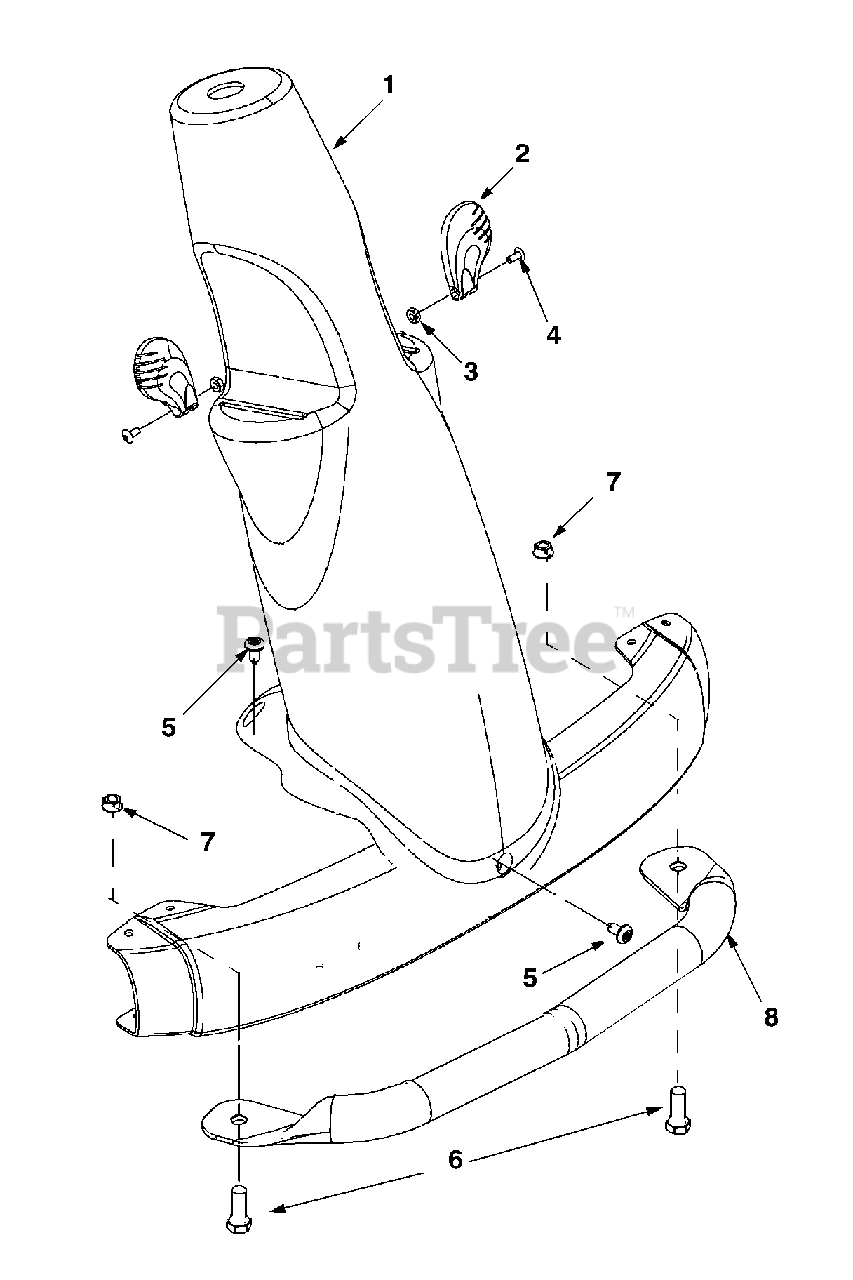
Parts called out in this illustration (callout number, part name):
1	Steering Column: Black
2	Control Knob
3	Hex Nut 8-32
4	Pan Head Machine Screw #8-32
5	Hex Screw TT 1/4-20 x .50"
6	Hex Screw 3/8-16 x 1.0"
7	Lock Nut
